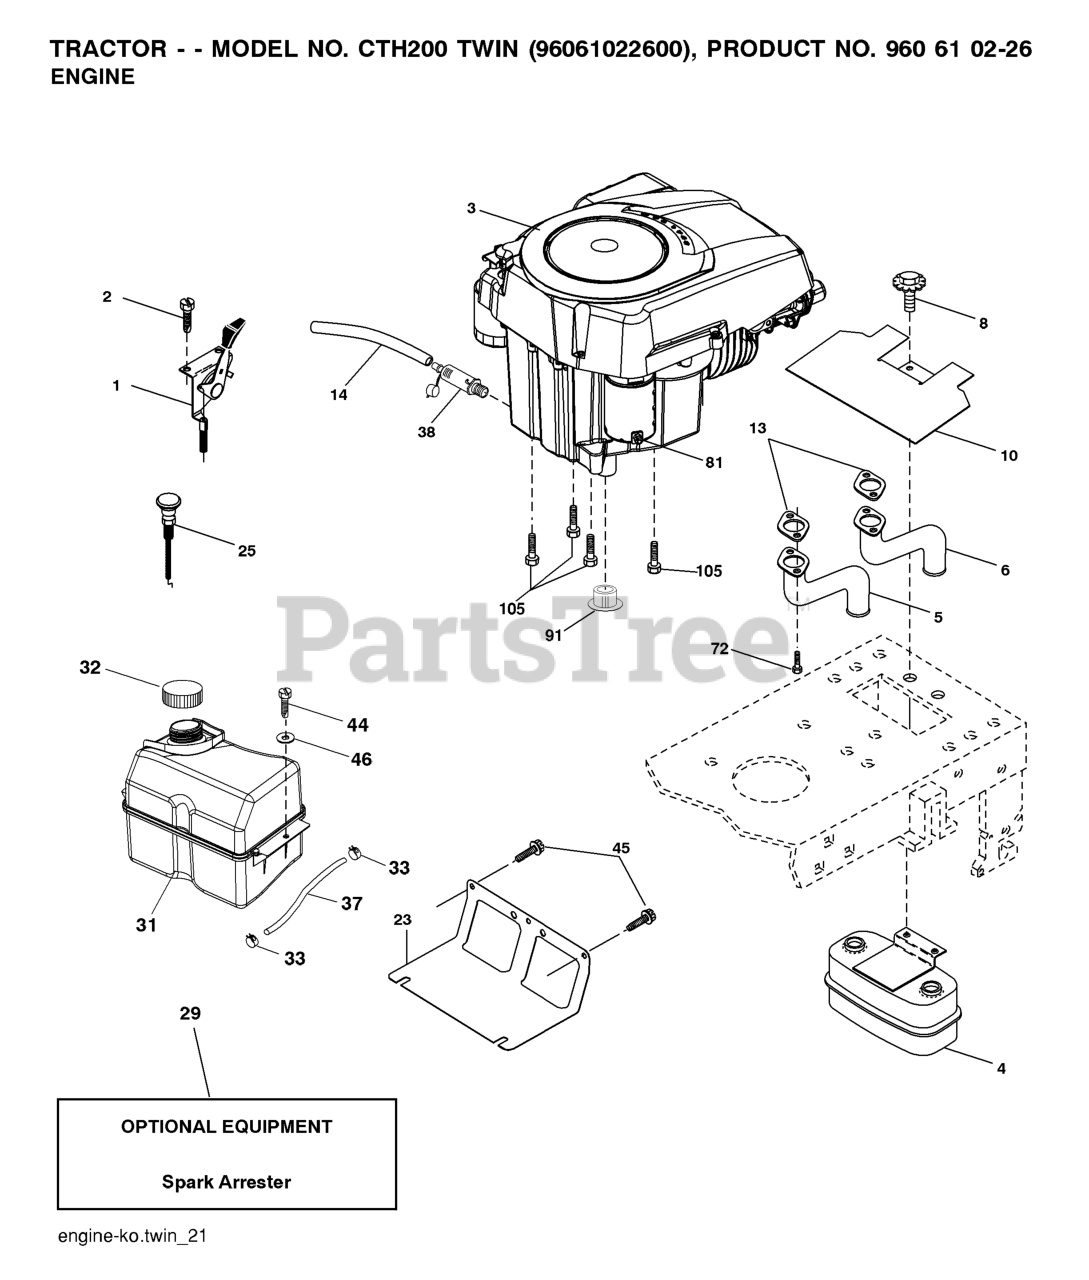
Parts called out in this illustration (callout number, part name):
1	THROTTLE CONTROL
2	SCREW
4	MUFFLER.TWIN.CYL.LOW.TONE
5	RP.PIPE-EXHAUST LH
6	RP.PIPE-EXHAUST RH
8	BOLT.5/16-18UNCX3/4 W/SEMS.BLK
10	RP SHIELD HEAT MUFFLER
13	GASKET.EXHAUST.KOHL.CV18-CV26
14	TUBE, DRAIN OIL ASM.
23	SHIELD.BROWNING.DBR.GUARD
25	CONTROL, CHOKE
29	KIT.SPARK ARRESTOR 794945 B&S
31	TANK.ASM.FUEL.FR.2.5GA.
32	FUEL CAP
33	HOSE CLAMP
37	LINE.FUEL.20
38	PLUG DRAIN OIL EASY
44	SCREW HEXWSHR 1/4-20X3/4
45	SCREW, 3/8-16X3/4
72	SCREW.SOCKET HD.5/16-1
81	NUT
91	BUSHING.1.375OD
105	SCREW 3/8-16X1
